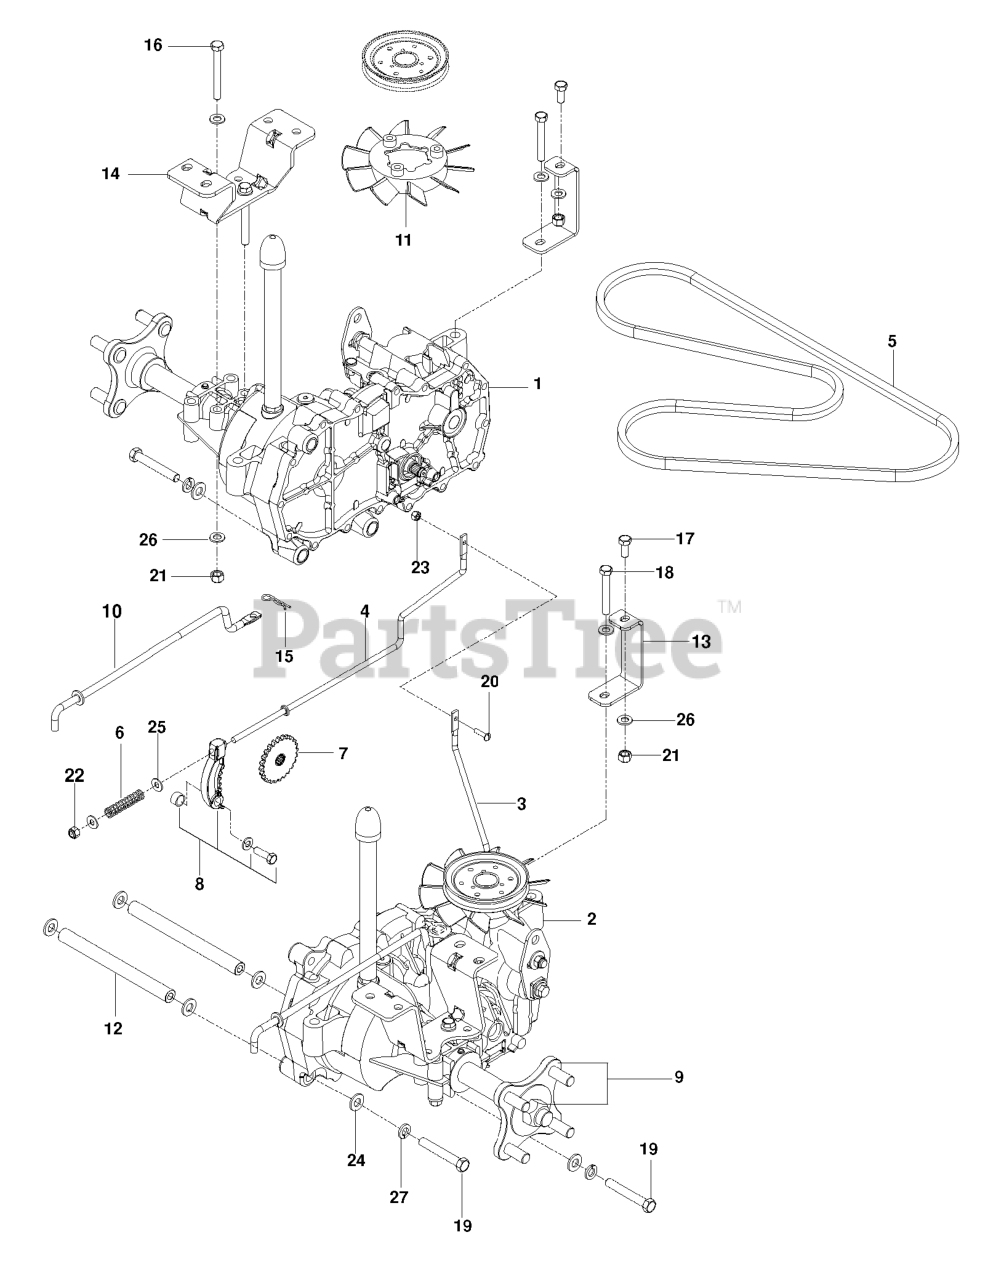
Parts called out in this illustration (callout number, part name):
1	HG_EZT, LT
2	HG_EZT, RT
3	LINKAGE.BRAKE.LT
4	LINKAGE, BRAKE RT
5	BELT, HYDRO PUMP
6	SPRING
7	HG_DISC COG BRAKE 51635
8	HG_KIT BRAKE ARM (EZT)
9	HG_KIT, HYDRO-GEAR HUB
10	LINKAGE, BYPASS, EZT
11	HG_HYDRO FAN 51365
12	SPACER TUBE, EZT
13	SUPPORT.FRONT.TRANS.PNTX431
14	BRACKET.EZT.MOUNT.REAR.PNTX431
15	HAIRPIN #2
16	BOLT HEX
17	BOLT.FIN.HEX.5/16-18X3/4
18	BOLT.FIN HEX 5/16-18UNC X2 1/4
19	SCREW.HEX HEAD.38-16 X 2.5
20	SCR #10-24 X 3/4
21	NUT.71038.31-18.HEX.NYLOCK
22	LOCKNUT.NYLOC.1/4-20
23	NUT 10-24 NYLOC
24	WASHER
25	WASHER
26	WASHER
27	LOCKWASHER
